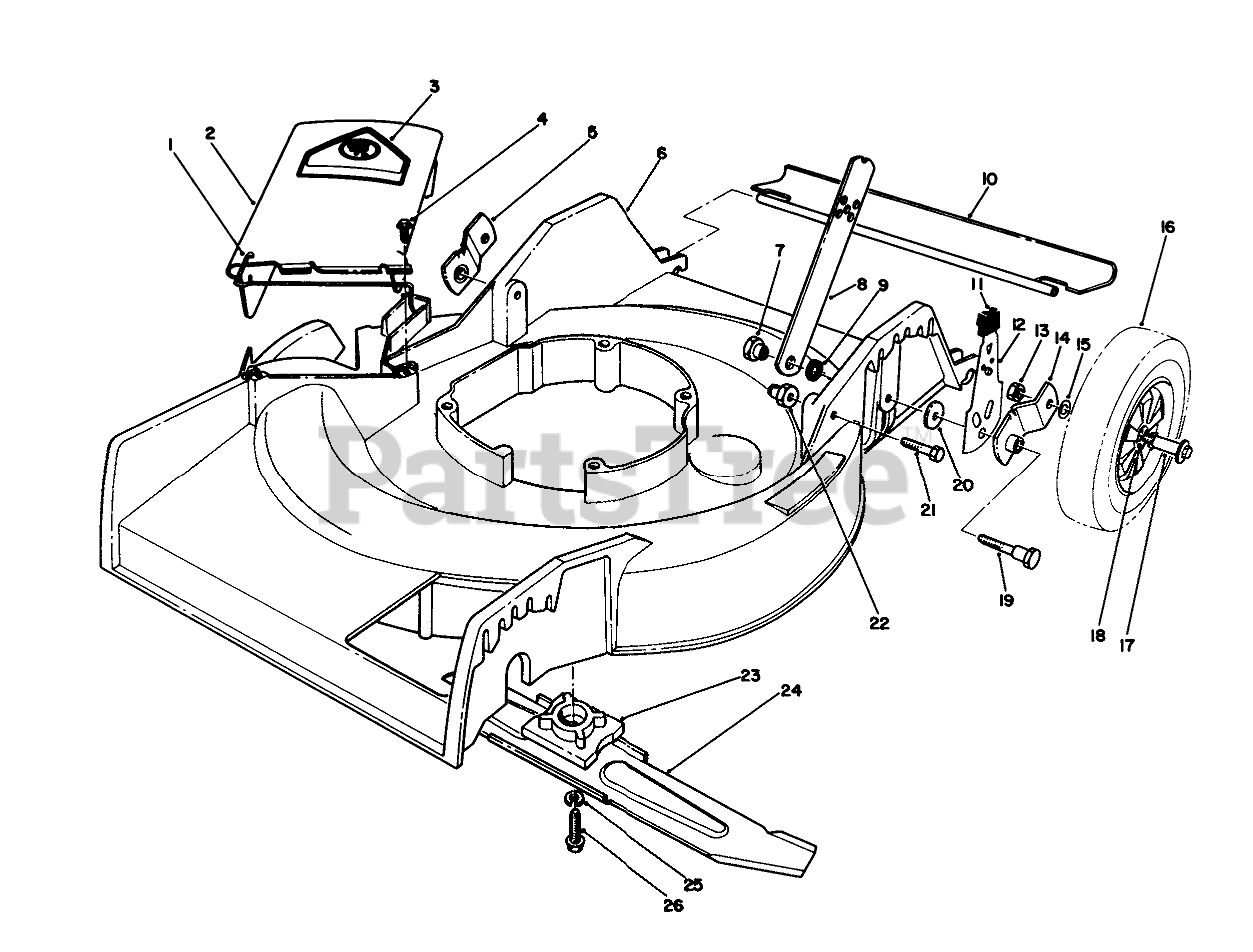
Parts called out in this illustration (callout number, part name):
1	SPRING HINGE
2	Deflector Assembly (Incl. Ref. #1 & 3)
3	DECAL-DANGER
4	SCREW-HWH
5	Pivot Arm
6	Housing-21" (Incl. Ref. #27)
7	HANDLE PIVOT NUT
8	HANDLE LATCH
9	SPACER
10	SHIELD - TRAILING
11	KNOB-ARM
12	REAR SPRING ARM ASM
13	Nut
14	Pivot Arm
15	WASHER
16	Wheel & Tire Assembly (Incl. Ref. #18)
17	BOLT-WHEEL
18	BUSHING
19	PIVOT SCREW
20	PIVOT WASHER
21	SCREW-HH
22	HANDLE PIVOT NUT
23	BLADE RETAINER
24	Blade
25	WASHER-LOCK
26	SCREW-HH
